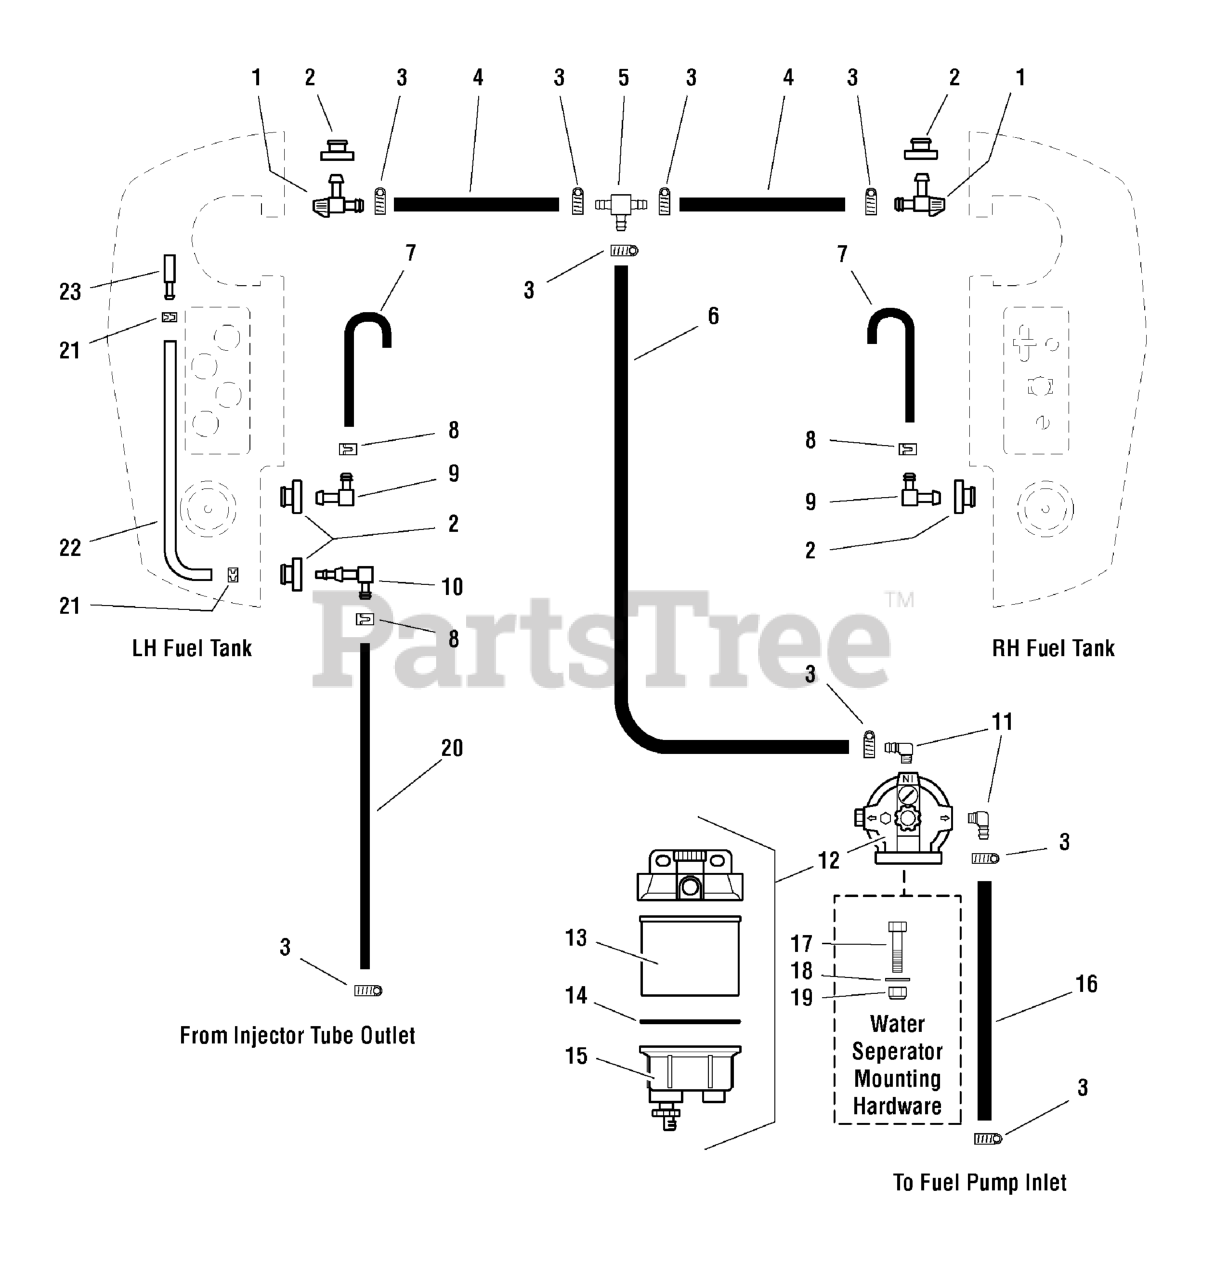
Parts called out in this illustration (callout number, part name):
1	VALVE, Fuel Shut-Off
2	BUSHING-FUEL TANK RED RUBBER
3	CLAMP, #4 Hose
4	HOSE, 36"
5	FITTING, TEE, 3/8" Hose
6	HOSE, 34"
7	1/4" Fuel Line, 20" Long
8	CLAMP, Hose
9	ELBOW FITTING
11	FITTING, 1/4" NPT, 90 Deg.
12	FILTER/WATER SEPARATOR ASSEMBLY, Complete
13	FUEL FILTER
14	O-RING SEAL
16	1/4" Fuel Line, 48" Long
17	BOLT, 3/8-16 X 1-1/2" GD5 CZ
18	WASHER, 3/8 SAE
19	NUT, 3/8-16 HEX NYLON LOCK
20	HOSE, 63"
22	HOSE ASSEMBLY
